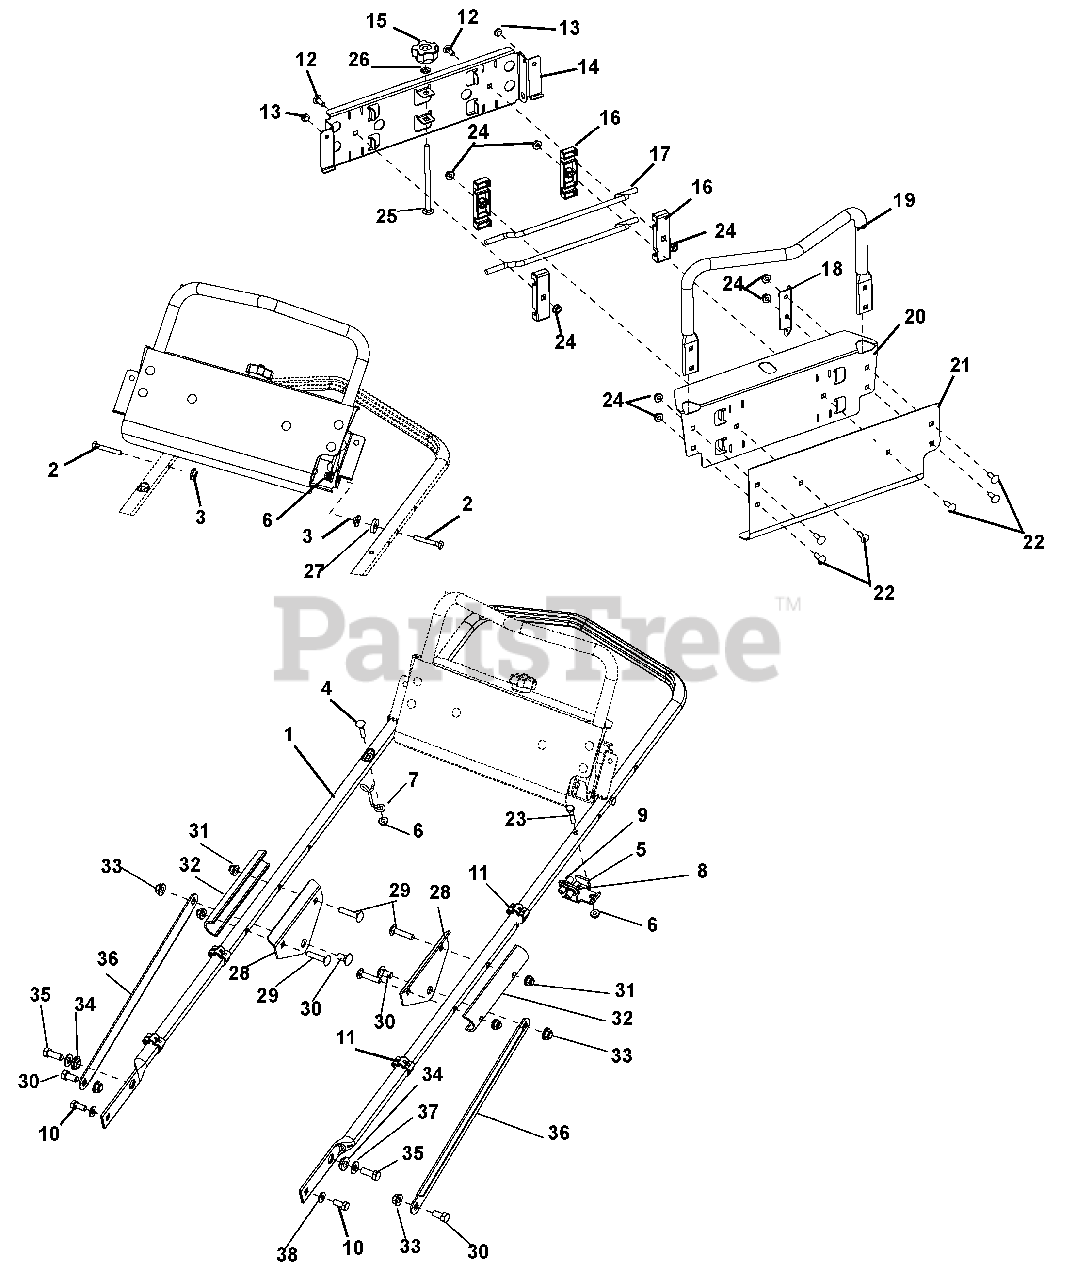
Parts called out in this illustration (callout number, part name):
1	HANDLEBAR,PRO 21
2	@BLT-HEX .25-20X1.75 GR5 YWZC
3	BSHG-FLG .265X.437X.250X.750
4	BLT-RDHDXLSQNK.25-20X1.25 G5ZC
5	BKT,CABLE ANCHOR
6	@NUT-LK-TOP-FLG .25-20 YWZC
7	GUIDE - PULLCORD
8	CABLE,OPC (DLX) KAWASAKI
9	CABLE-DRIVE
10	@BLT-HEX .31-18X.75 GR5 YWZC
11	CONDUIT CLIP
12	@BLT-RDHDSQNK .25-20X1.00 G5YZ
14	PLATE,HINGE
15	KNOB-CLAMPING, .312-18 NYLOC
16	CLAMP,4-BAR
17	ROD,4-BAR
18	CABLE ANCHOR
19	BAIL .750 TUBE
20	COVER,OP CONTROL
21	COVER,SHEETMETAL
22	@BLT-RDHDSQNK .25-20X1.00 G5YZ
23	@BLT-HEX .25-20X1.25 GR5 YWZC
24	@NUT-SPNLK-FLG .25-20 YWZC
25	BLT-RDHDSQNKFTH.31-18X5 GR5YZC
26	NUT-PUSH .312
27	WSHR-FL-STL .328X.87X.179 YWZC
28	PLATE,HANDLEBAR
29	@BLT-RDHDSQNK .31-18X1.50 G5YZ
30	@BLT-HEX .38-16X.75 GR5 YWZC
31	@NUT-LK-NYL-FLG .31-18 YWZC
32	SERVICE BAR BRACE
33	@NUT-LK-NYL-FLG .38-16 YWZC
34	BSHG-FLG .406X.88X.270X.140
35	@BLT-HEX .38-16X1.00 GR5 YWZC
36	STRAP,HANDLEBAR
37	@WSHR-FL-STL.406X.812X.065 YWZ
38	@WSHR-FL-STL.344X.688X.065YWZC
